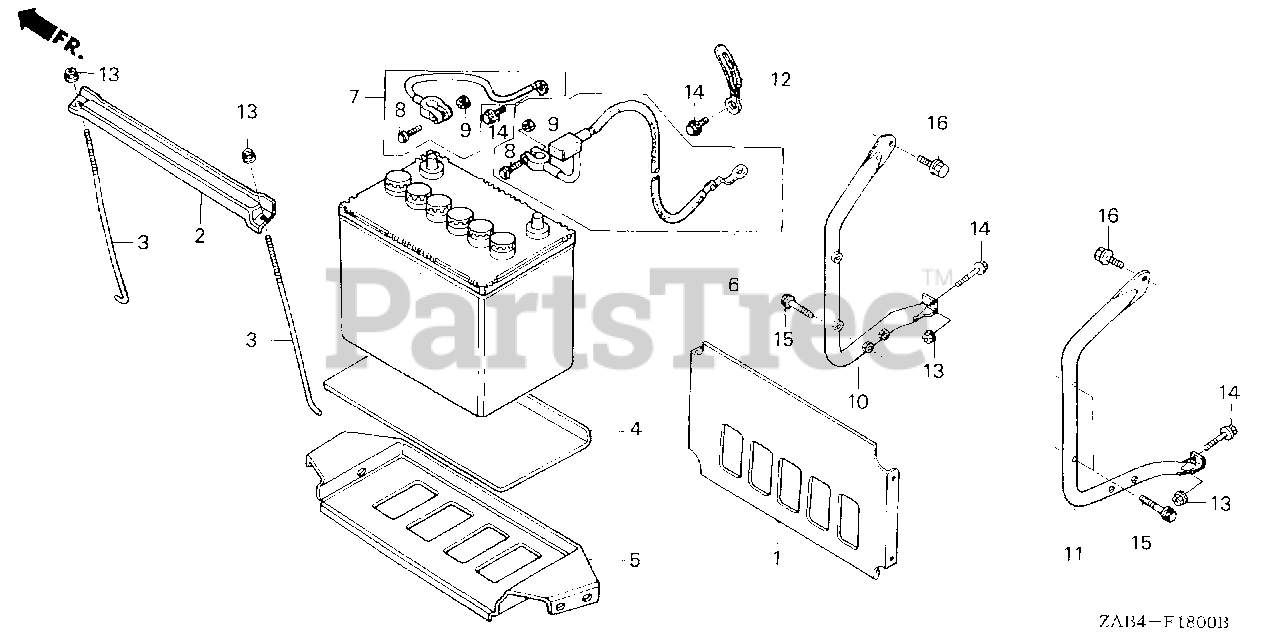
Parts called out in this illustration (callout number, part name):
1	PLATE, BATTERY GUARD
2	PLATE, BATTERY SETTING
3	BOLT, BATTERY SETTING (220MM)
4	PLATE, BATTERY
5	BASE, BATTERY TRAY
6	CABLE ASSY., STARTER
7	CABLE ASSY., GROUND
8	BOLT, BATTERY TERMINAL
9	NUT, BATTERY TERMINAL
10	GUARD, FR. BATTERY *NH105* (MAT BLACK)
11	GUARD, RR. BATTERY *NH105* (MAT BLACK)
12	CLIP, HEAD
13	NUT, FLANGE (6MM)
14	BOLT, FLANGE (6X12)
15	BOLT, FLANGE (6X28)
16	BOLT, FLANGE (8X16)
